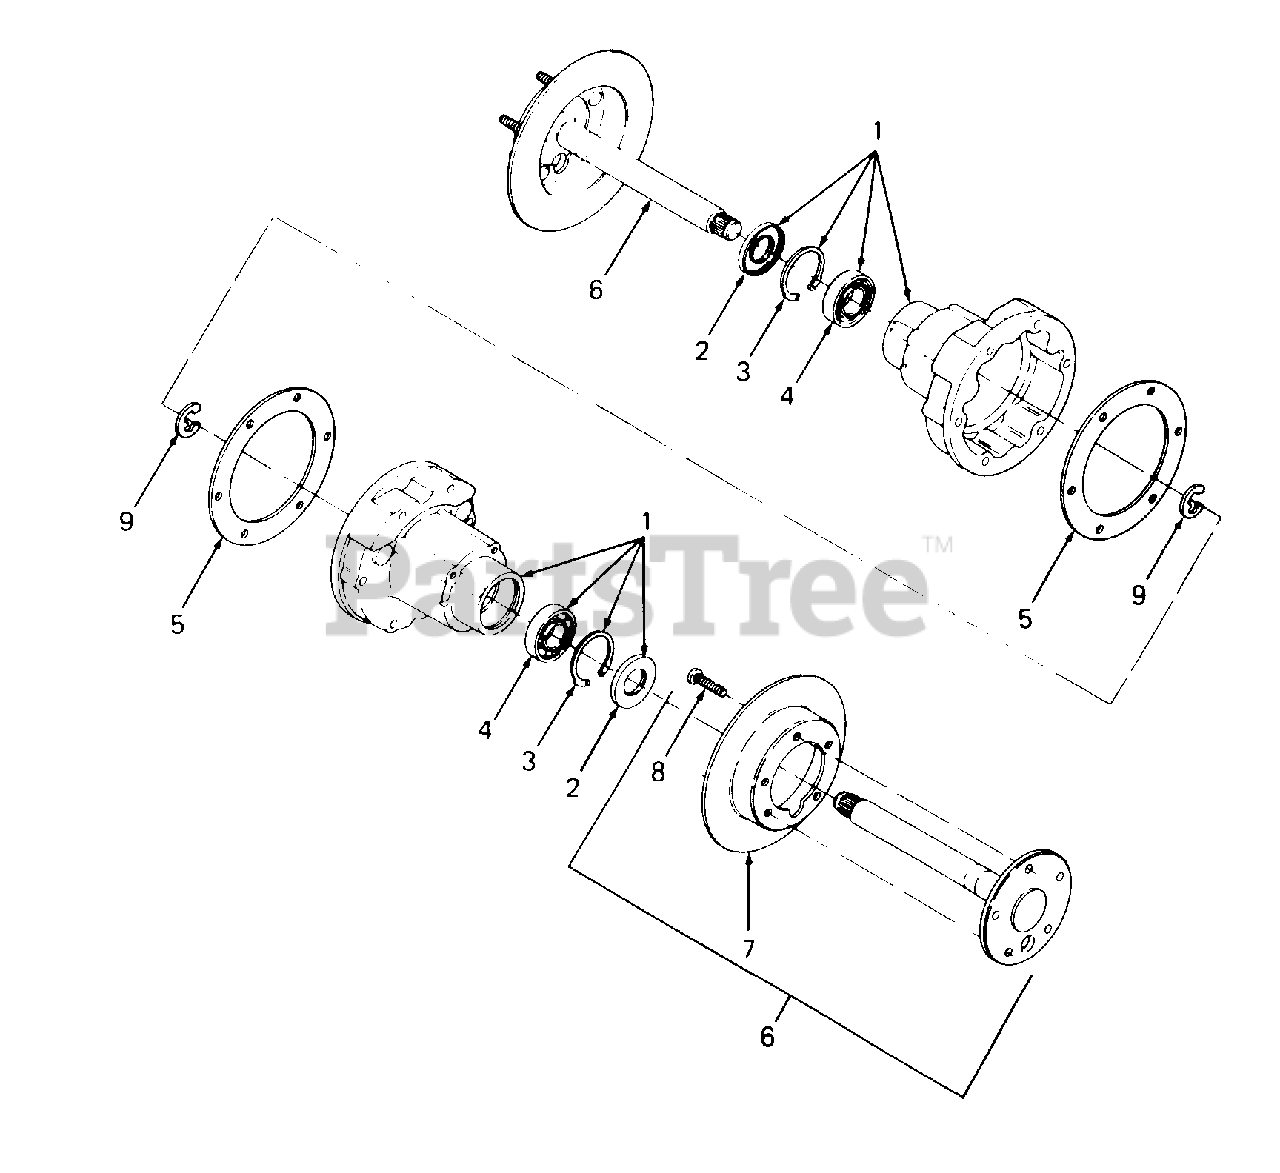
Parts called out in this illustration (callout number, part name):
1	Carrier Assy, Rear Axle
2	Seal, Oil
3	Ring, Retainer
4	Bearing, Ball
5	Gasket, Carrier
6	Axle Assy, Rear
7	Disc, Break
8	Bolt, Lug
9	Retainer, E-Ring
